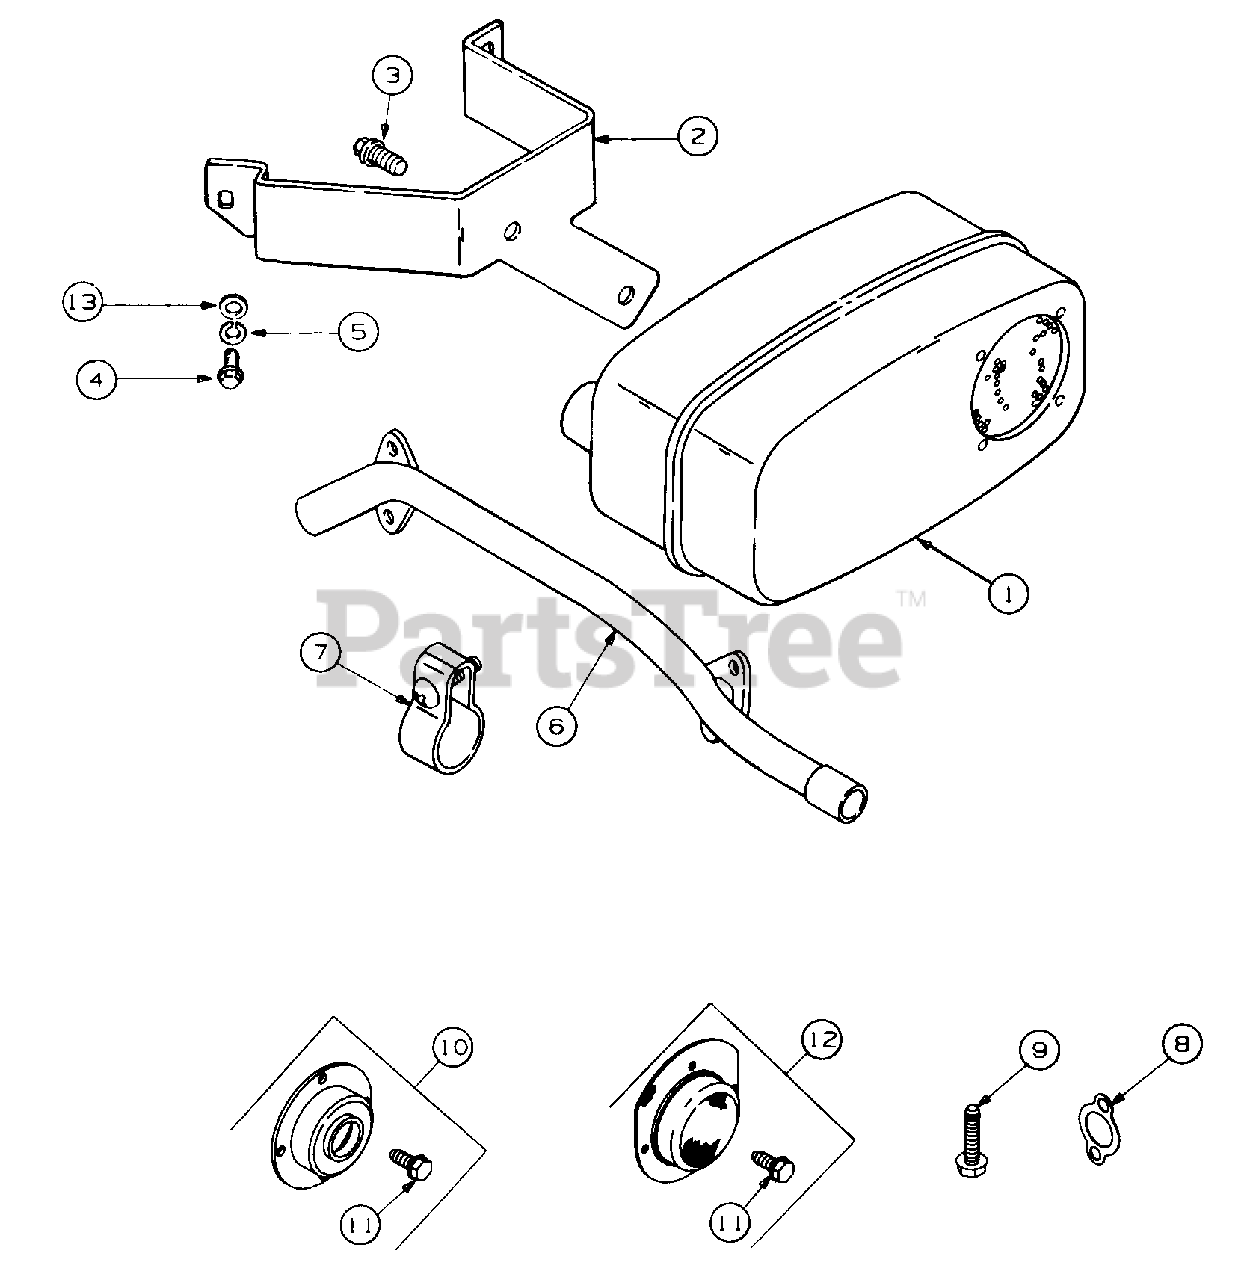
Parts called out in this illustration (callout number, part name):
1	Muffler
2	Bracket, Muffler
3	Screw, Hex Wash Hd Tap, 1/4-20 X .50 Lg
4	Screw, Hex Cap, M6-1.0 X 20 mm Lg GR10.9
5	Washer, Lock, 1/4
6	ManHold, Exhaust
7	Clamp, Muffler
8	Gasket, Exhaust Manifold
9	Screw, Sem
10	Deflector, Exhaust
11	Screw, Sem
12	Arrester, Spark
13	Washer, Flat .281 x .75 x .105 Thk
